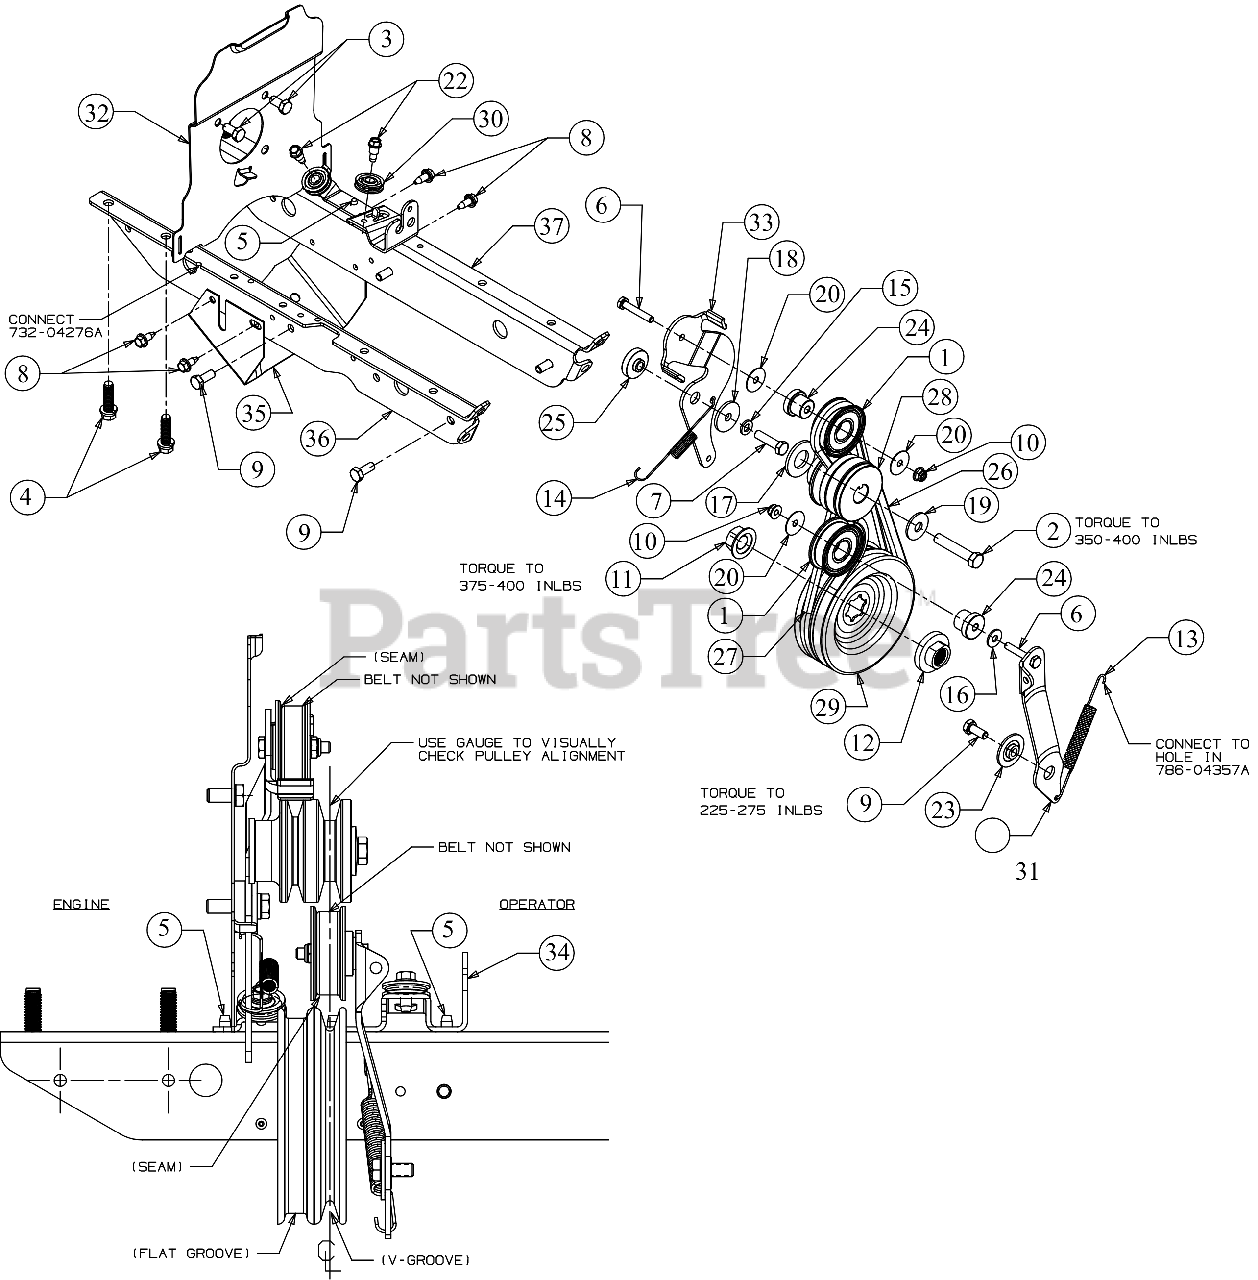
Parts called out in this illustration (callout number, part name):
1	IDLER PULLEY ASSEMBLY
2	HEX SCREW 3/8-24 X2.00
3	HEX SCREW 5/16-24 X .62
4	SCREW 3/8-16 X 1.250
5	SCREW 1/4-20 X.500
6	SCREW 1/4-20 X 1.50 GR.5
7	SCREW 5/16-24 X 1.25 GR5
8	SCREW 1/4-14 X .625
9	SCREW 5/16-18 X .750
10	FLANGE LOCK NUT
11	FLANGE NUT W/HUB
12	PULLEY HUB
13	RETURN SPRING
14	EXTENSION SPRING
15	LOCK WASHER 5/16
16	FLAT WASHER .28 ID X .74 OD X .063
17	FLAT WASHER
18	WASHER-5/16 X 1.25X 1.27
19	BELL WASHER
20	FLAT WASHER
22	SHOULDER SCREW
23	PIVOT IDLER SPACER
24	SHOULDER SPACER
25	PIVOT IDLER SPACER
26	V-BELT FWD DRIVE 4L X 25.375
27	V-BELT REV DRIVE 3L X 29.125
28	ENGINE PULLEY
29	TRANSMISSION PULLEY
30	CABLE GUIDE ROLLER
31	FORWARD IDLER BRACKET
33	REVERSE IDLER BRACKET
